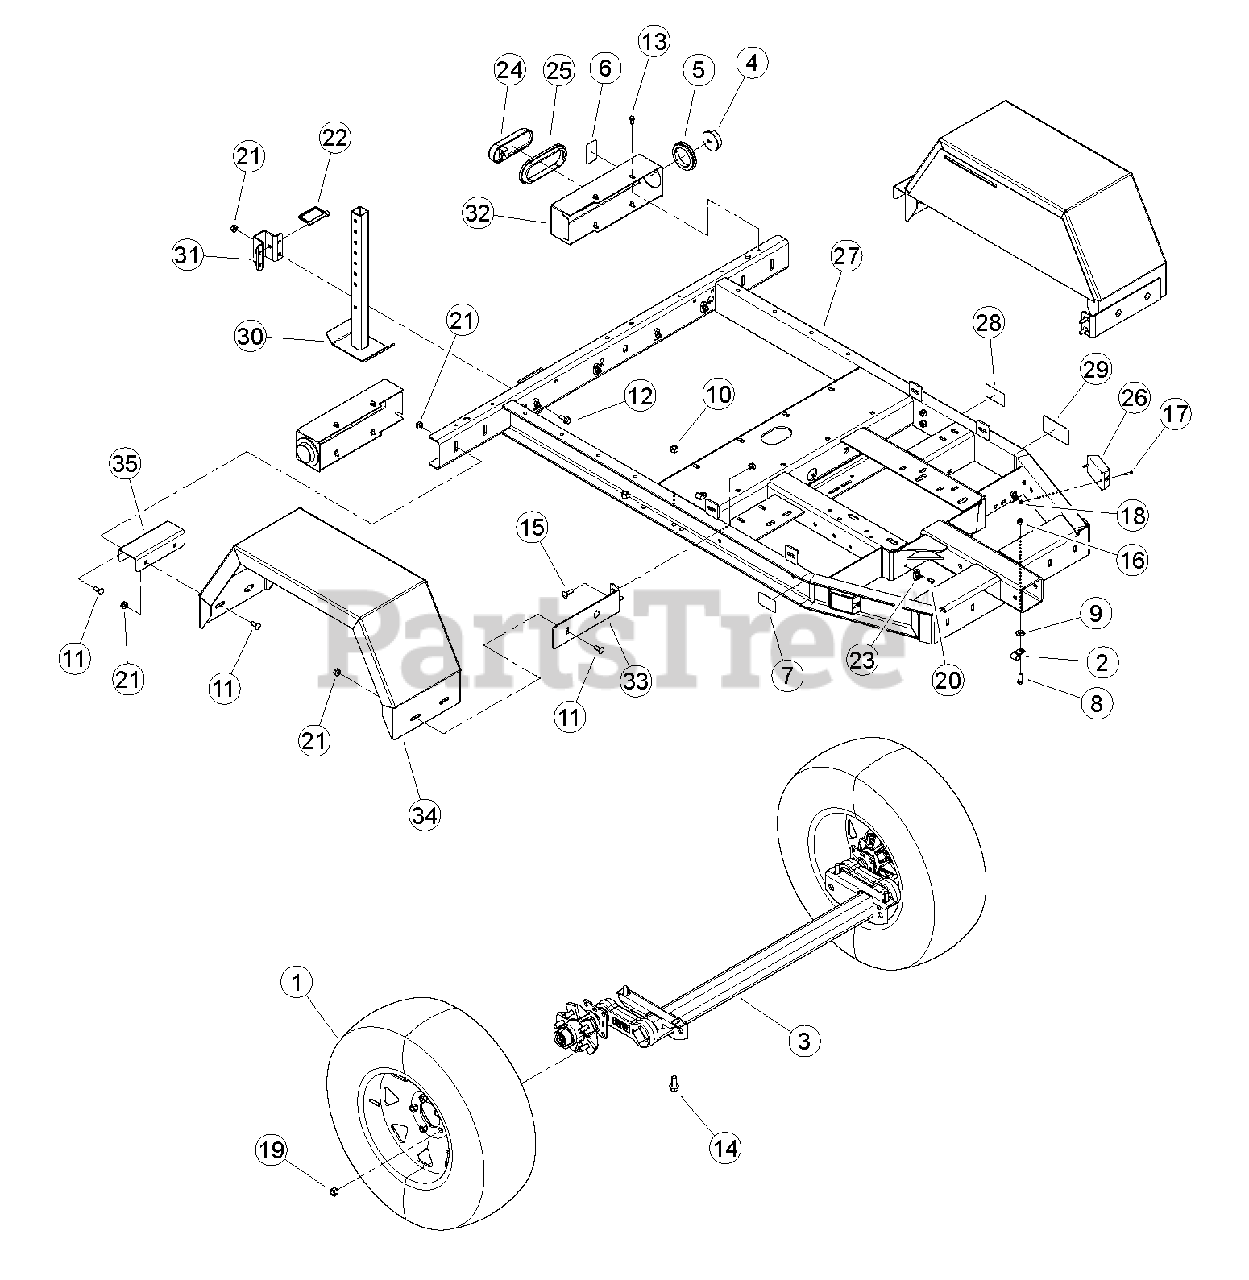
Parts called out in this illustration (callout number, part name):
1	ASSEMBLY, 15 INCH TIRE + WHEEL
2	CLAMP, 9/16 COATED
3	AXLE, 2500 LB TORSION
4	LIGHT, RED CLEARANCE
5	GROMMET, CLEARANCE LIGHT
6	REFLECTOR, WIDE ANGLE RED
7	REFLECTOR, WIDE ANGLE AMBER
8	BOLT, 3/8 X 1 HEX HD GR5 ZP
9	WASHER, 3/8" FLAT ZP
10	NUT, 1/2" CENTERLOCK GRB ZP
11	BOLT, 3/8 X 1" GR5 CRG NC ZP
12	BOLT, 3/8 X 1 FLANGE NC
13	SCREW, 11/32 X 7/8 HWH AB THREAD ZP
14	BOLT, 1/2 -13 X 1-1/4 FLANGE NC
15	BOLT, 3/8 X 1-1/4" GR5 CRG NC ZP
16	NUT, 3/8" NE NYLOCK ZP
17	SCREW, MCH 10-24 X 1" RND HD PHL ZP
18	NUT, 10/24 NYLOCK TYPE NM ZP
19	NUT, 1/2-20 WHEEL
20	RIVET, AL BLIND 1/4 X 3/4 DOME HEAD
21	NUT, 3/8-16 NYLOCK FLANGE
22	PIN, 3/8 X 2-3/4" SNAP
23	CLAMP, CABLE MOUNT
24	TAIL LIGHT, OVAL LED
25	GROMMET, OVAL TAIL LIGHT
26	LIGHT, AMBER MARKER
27	ASSEMBLY, CH611DH TRAILER/DECALS
28	DECAL, P215/70R15 100 LB LOAD RATING
29	DECAL, EPA EMISSION
30	WELDMENT, REAR STABILIZER
31	GUIDE, TRAILER SUPPORT
32	BRACKET, TAILLIGHT
33	BRACKET, FENDER
34	WELDMENT, CHIPPER FENDER
35	PLATE, FENDER SPACER
